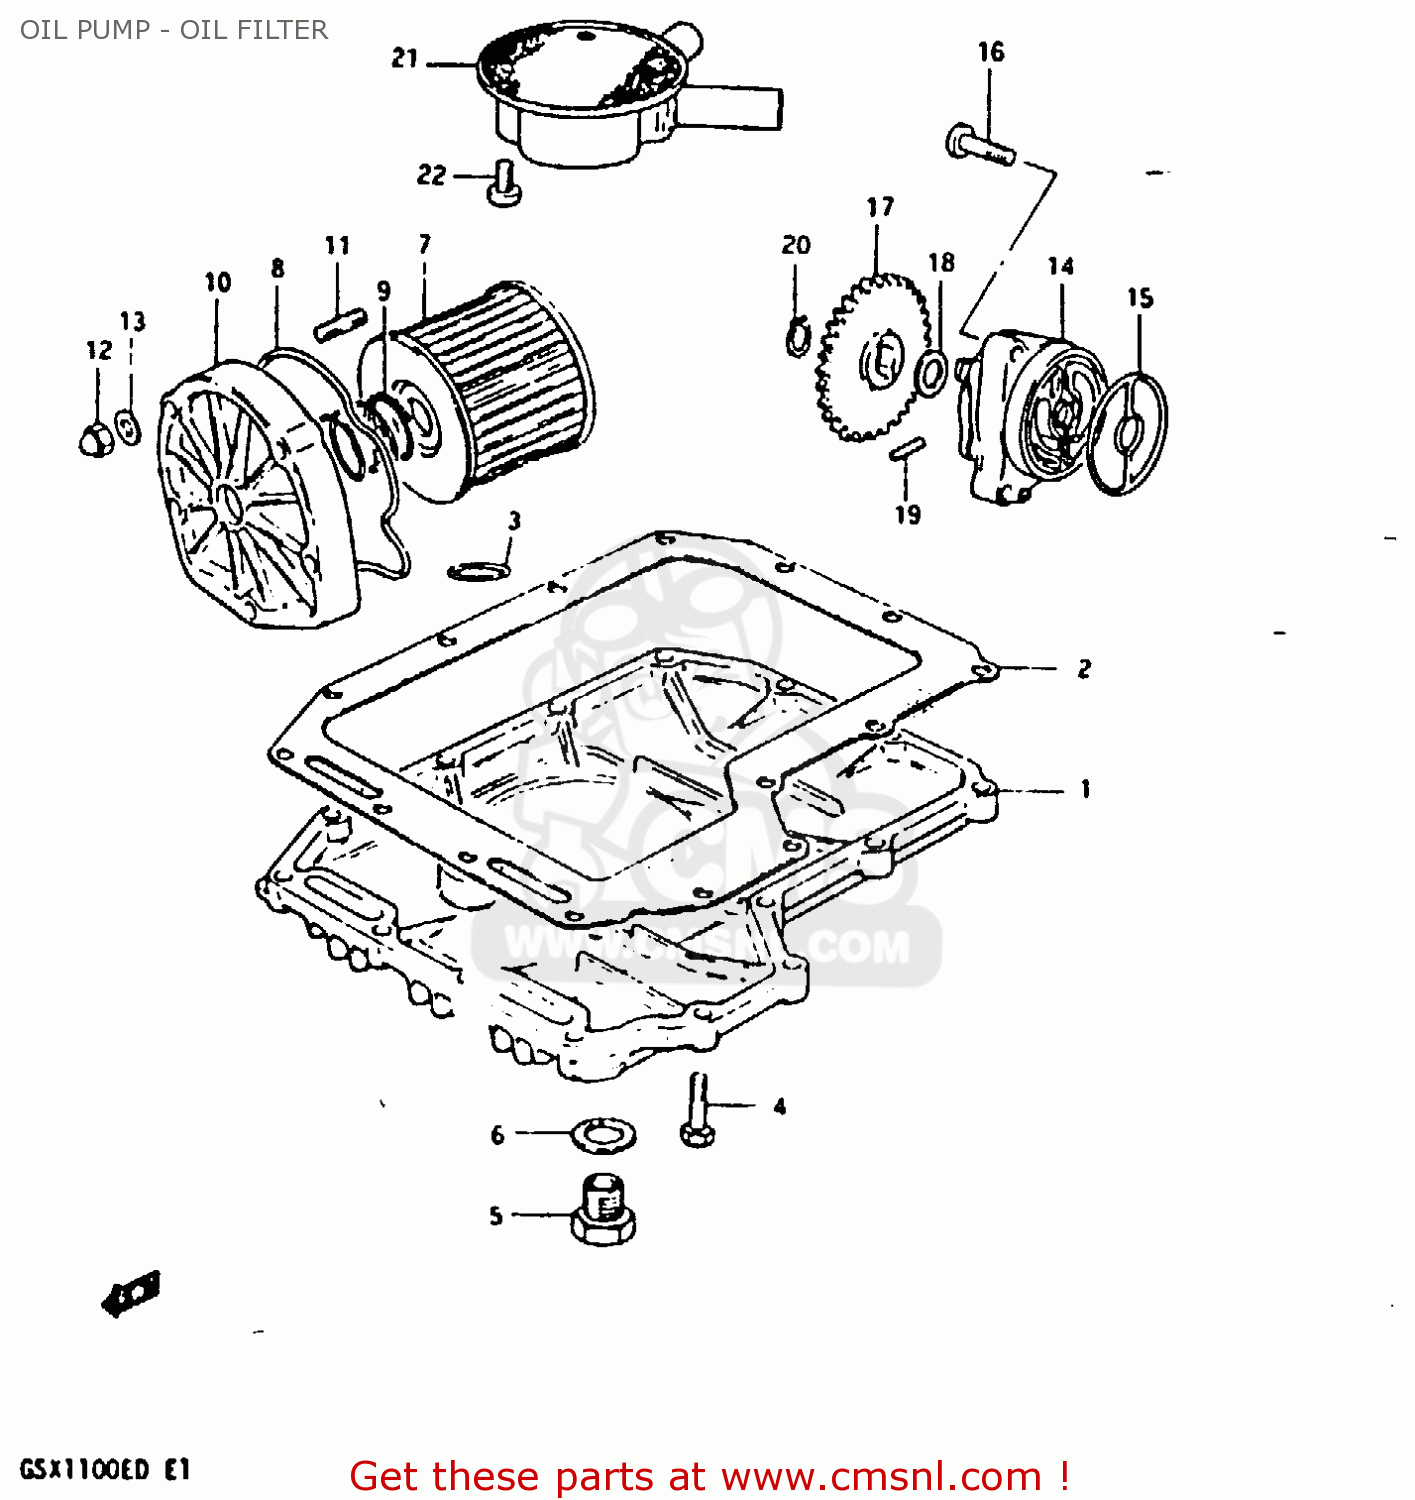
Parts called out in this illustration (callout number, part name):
1	PAN,OIL
2	GASKET,OIL PAN (MCA)
3	O RING(D:3.2,ID:12.9)
4	BOLT
5	PLUG
6	GASKET(14X19.2X2) (NAS)
7	FILTER ASSY,ENGINE OIL
8	O RING,OIL FILTER CHAMBER CAP
9	SPRING
10	CAP,ENGINE OIL FILTER
11	STUD 6X25
12	NUT
13	WASHER
14	PUMP ASSY,ENGINE OIL
15	O-RING,OIL PUMP
16	BOLT(6X32)
17	GEAR,ENG OIL PUMP DRIVEN(NT:33
18	SHIM
19	PIN(4X15.8)
20	CIRCLIP
21	STRAINER,ENGINE OIL
22	SCREW 6X12
